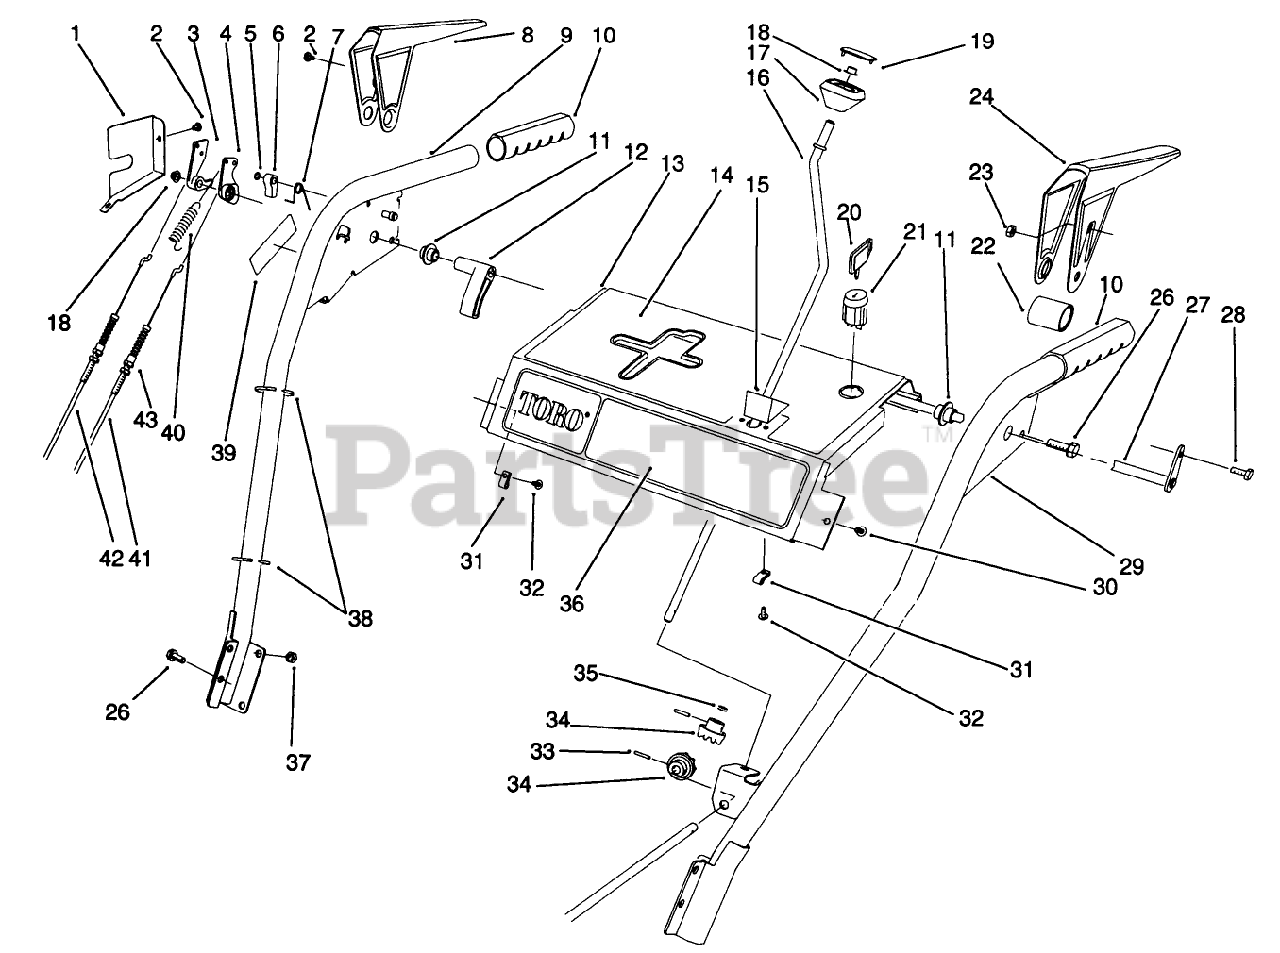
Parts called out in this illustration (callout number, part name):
4	CAM-RELEASE
5	RING-RETAINING
6	LATCH-LOCKING
7	SPRING-TORSION
10	GRIP-HANDLE
11	BUSHING-LEVER
12	LEVER-TRIP
15	PLATE-GUIDE
16	CRANK-ROD, CHUTE
17	KNOB-CONTROL, CHUTE
18	NUT-PUSH
19	COVER-KNOB
20	KEY-IGNITION
21	SWITCH
22	SPACER-LEVER, TRACTION
23	NUT-LOCK, NI
26	SCREW-HHF
27	CROSS ROD ASM
28	SCREW-HWH
30	SCREW-HWHTF
32	SCREW-PPH
33	PIN-SPRING
34	GEAR-UNIVERSAL
35	WASHER-RUBBER
36	DECAL-FRONT PANEL (624)
37	NUT-LOCK, NI
38	TIE-CABLE
39	DECAL - ADJ WARNING
41	CABLE-TRACTION
42	CABLE-IMPELLER
43	NUT-LOCK, NI
